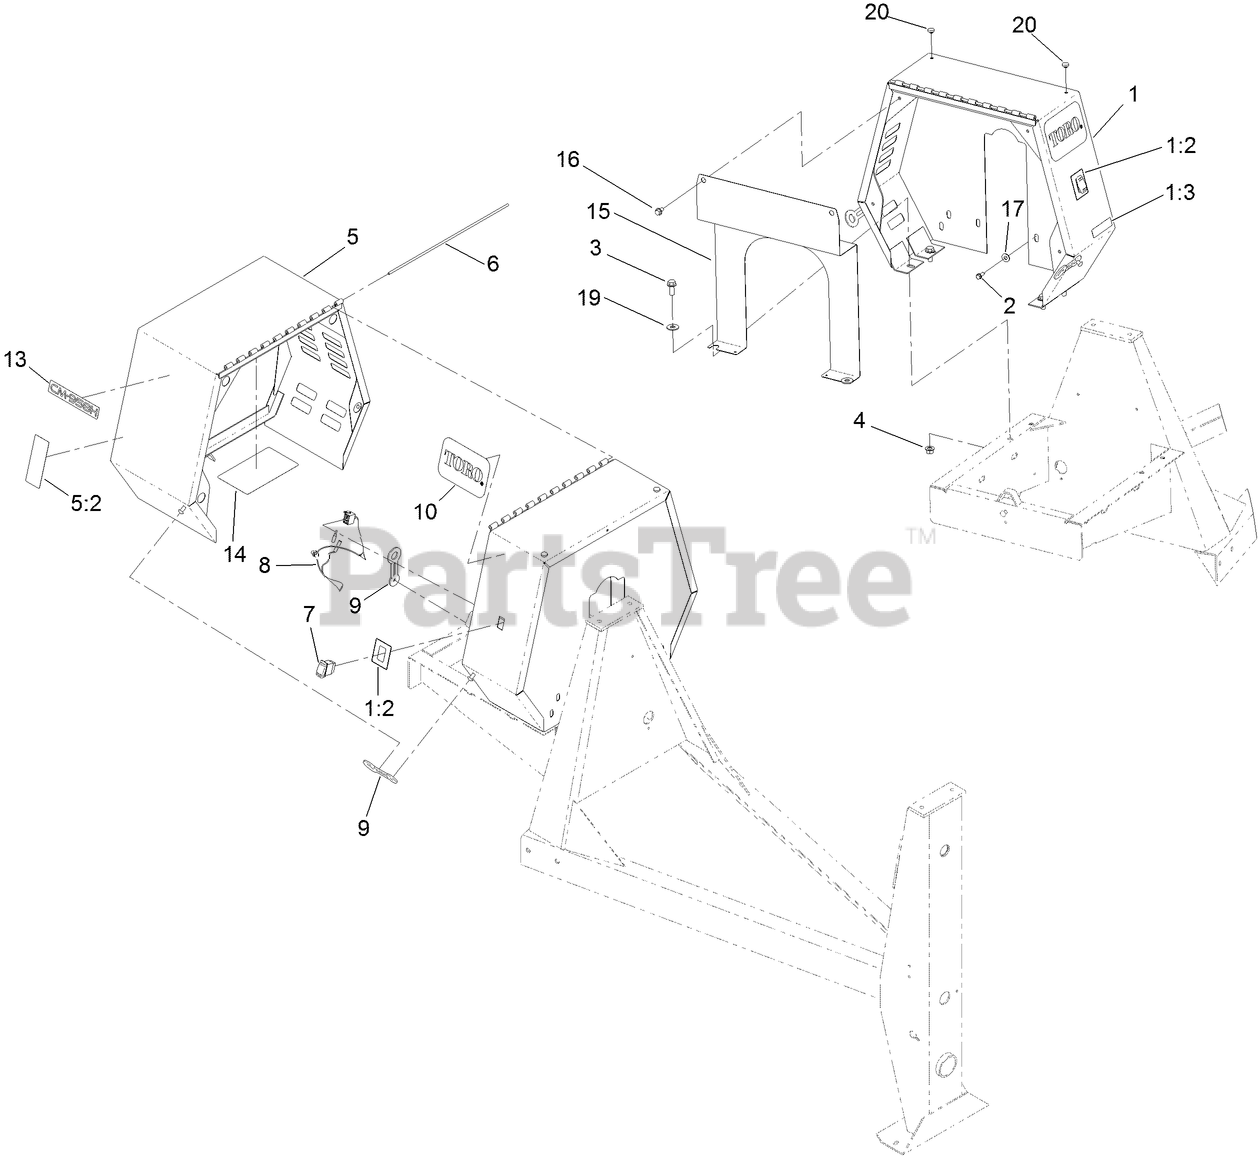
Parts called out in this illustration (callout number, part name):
1	STATIONARY COWL ASM
1:2	DECAL-STOP, ENGINE
1:3	DECAL-ARRESTER, SPARK
2	SCREW-THD ROLL, HWH
3	SCREW-HHF
4	NUT-LOCK
5	MOVABLE COWL ASM
5:2	DECAL-WARNING
7	SWITCH
8	HARNESS-WIRE, MIXER
9	LATCH-RUBBER
10	DECAL
14	DECAL-SERVICE
15	PLATE-ENGINE
16	SCREW-HWH
17	WASHER-FLAT
19	WASHER-FLAT
20	BUMPER
